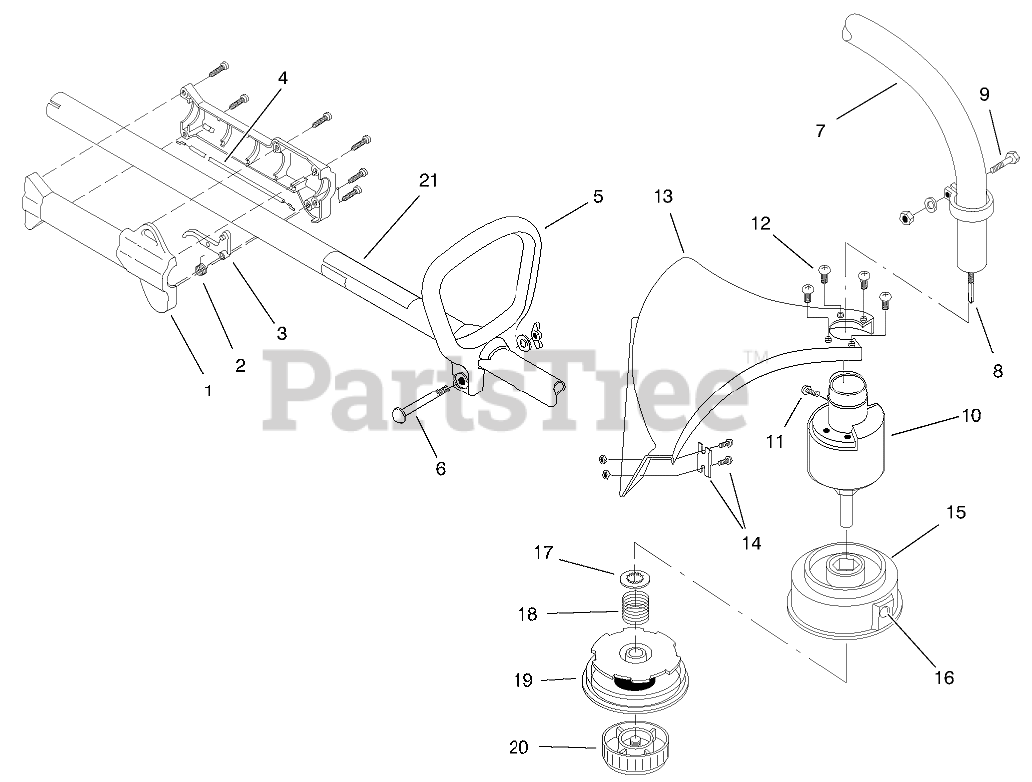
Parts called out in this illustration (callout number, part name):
1	ASM.-THROTTLE HSG/TRIGGER
2	THROTTLE TRIGGER SPRING
3	TRIGGER - THROTTLE
4	ASM-HOUSING,THROTTLE CABLE (SERVICE)
5	D-HANDLE
6	HARDWARE - D-HANDLE
7	DRIVE SHAFT HSG ASM
8	Drive Shaft
9	CLAMP ASM - UPPER
10	BUSHING HSG ASM
11	ANTI-ROTATION SCREW
12	Guard Mounting Screw
13	Shield & Blade ASM (Includes Ref #14)
14	BLADE ASM
15	OUTER SPOOL EYELET ASM
16	EYELET
17	RETAINER WASHER(SET OF 10)
18	SPRING
19	REEL - INNER
20	SMALL BUMP KNOB ASM
21	DECAL - SAFETY SYMBOLS
